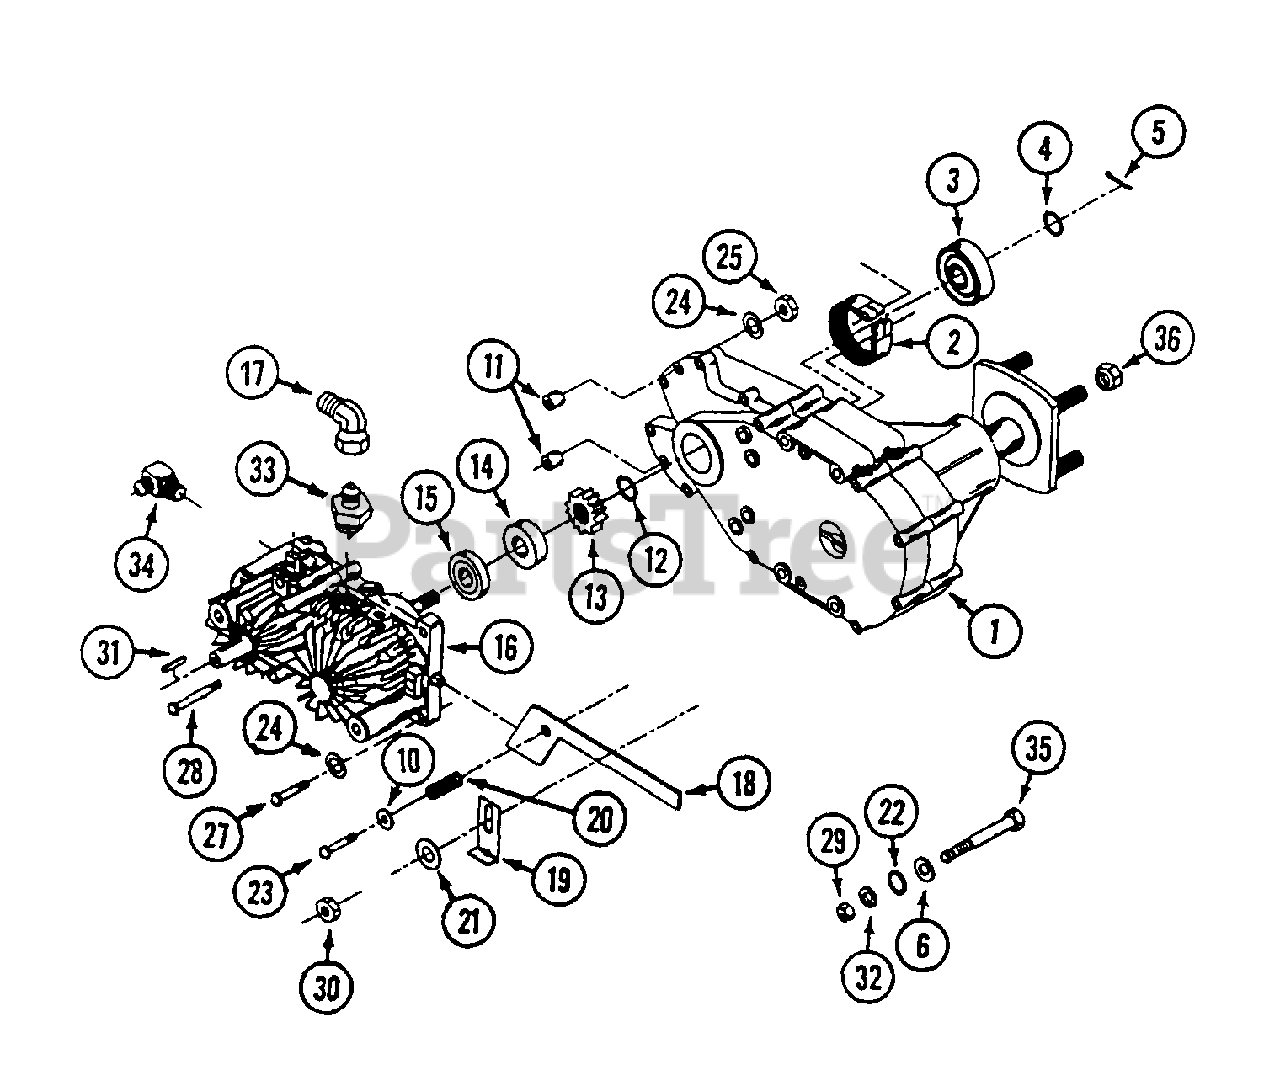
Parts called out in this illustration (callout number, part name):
1	TRANSMISSION - ZT
5	PIN - cotter 3/32" x 3/4"
6	WASHER - .40" x .81"
10	WASHER - 1/4"
12	RING - snap
14	BEARING
16	PUMP - hydro L.H.
17	FITTING - 90° male to female
18	LEVER - transmission dump LH.
19	BRACKET - dump lever stop
20	SPRING - compression
21	WASHER - 3/8"
22	"O" RING - mounting
23	BOLT - dump lever
24	LOCKWASHER - 5/16"
25	NUT - 5/16" - 18
27	BOLT - 5/16" - 18 x 1-3/4"
28	BOLT - 5/16" - 18 x 7-1/2"
29	NUT - 3/8" - 16
30	NUT - 3/8" - 16 lock
31	KEY-5 x 5 x 25mm
32	LOCKWASHER - 3/8"
33	FITTING - male adaptor pump outlet
34	FITTING - male adaptor 90° pump inlet
35	BOLT - 3/8" - 16 x 3-1/2" mounting
35	BOLT - 3/8" - 16 x 4" mounting
36	NUT - lug 1/2" - 20
